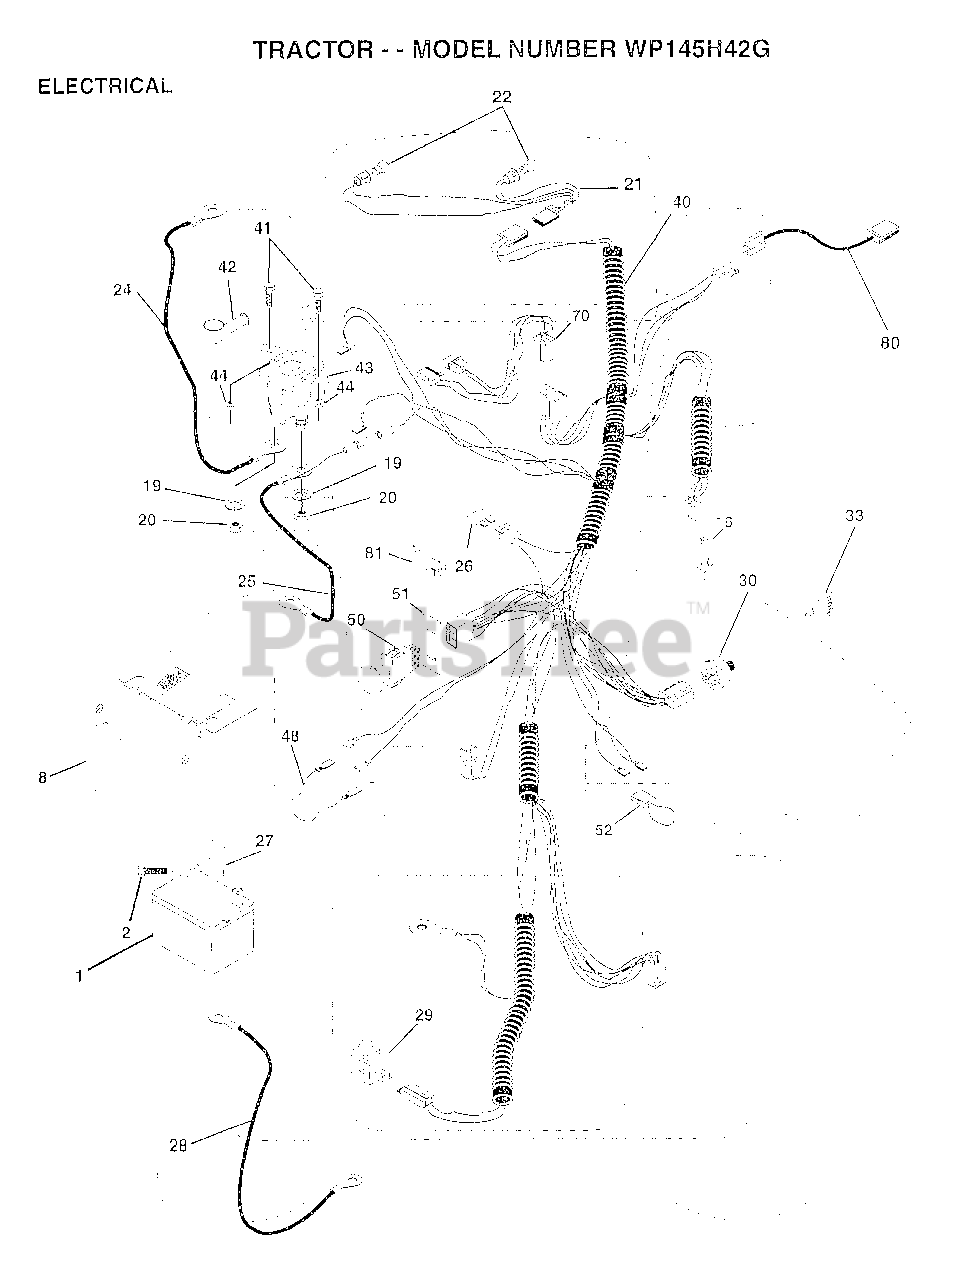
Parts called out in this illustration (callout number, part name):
2	BOLT LT
8	"CASE,BATTERY.MECH"
16	SWITCH INTERLOCK
20	NUT
21	HARNESS.ASM.LIGHT.W/4152J
22	HEADLAMP BULB
24	CABLE.BTRY.6GA.RD
25	CABLE.BTRY.6GA.38
26	FUSE.15 AMP
27	NUT
28	CABLE T
29	SWITCH.PLUNGER
30	SWITCH.IGN.
33	KEY MLD GEN DELTA
40	HARNESS
41	BOLT HXHD FIN
44	NUT HXKEP 1/4X20
48	ADAPTER AMMETER
50	PTO SWITCH.BLK
51	RING RETAIN PTO
52	PROTECTION LOOP
70	HARNESS.ENGINE.B&S
80	HARNESS.CLUT.EVX.
81	RELAY ASSY T
